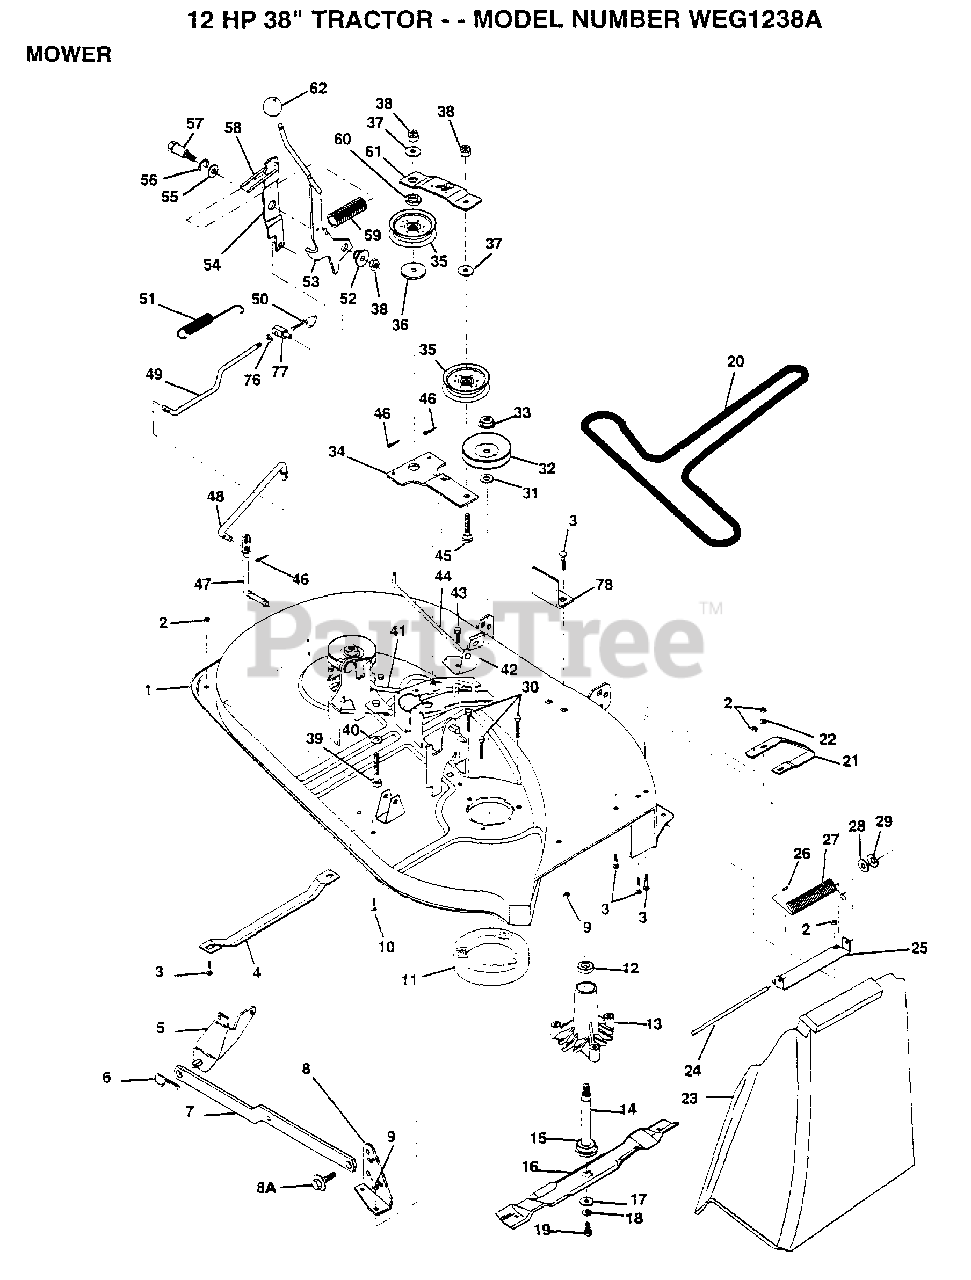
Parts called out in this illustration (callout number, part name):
2	NUT
3	BOLT
4	RUNNER-LH M
5	BRKT ASM SWAY BAR
8	BRKT DECK SW BAR
8A	BOLT SHD 5/16-18
9	NUT
10	BOLT
11	STRIPPER RND MWR
12	BEARING
13	HSG ASM MANDREL
15	BEARING.BALL
16	"BLADE.38""V.MULCH"
17	WASHER.HARD.BLADE
19	BLADE BOLT
20	V BELT
21	RUNNER RH
22	WASHER M
23	DEFLECTOR-SHLD T
24	ROD-HINGE T
25	BRKT DEFLECTOR
26	CAP-SLEEVE LT
27	SPRING TORSION
28	WASHER
29	NUT PUSH M
31	WASHER
34	IDLER ARM ASSY
35	FLAT IDLER PULLEY
36	SPACER RETAINER
37	WASHER GT
39	BOLT
40	WASHER GT
41	BRAKE ROD LH
42	BRAKE ROD
43	SCREW
44	BRAKE ROD RH
45	BOLT
47	PIVOT ROD
48	CLUTCH ROD SECOND
49	ROD CLUTCH 38/42
50	RETAINER M
51	RETURN SPRING
52	BUSHING
54	CLUTCH ARM SECOND
55	WASHER
56	RING
57	SHOULDER BOLT
58	SPRING KEEPER
60	RETAINER SPACER
61	IDLER ARM STIFF
62	KNOB T(3/8 HOLE)
76	NUT
77	TRUNION ADJ
78	UPSTOP DECK FT 38
